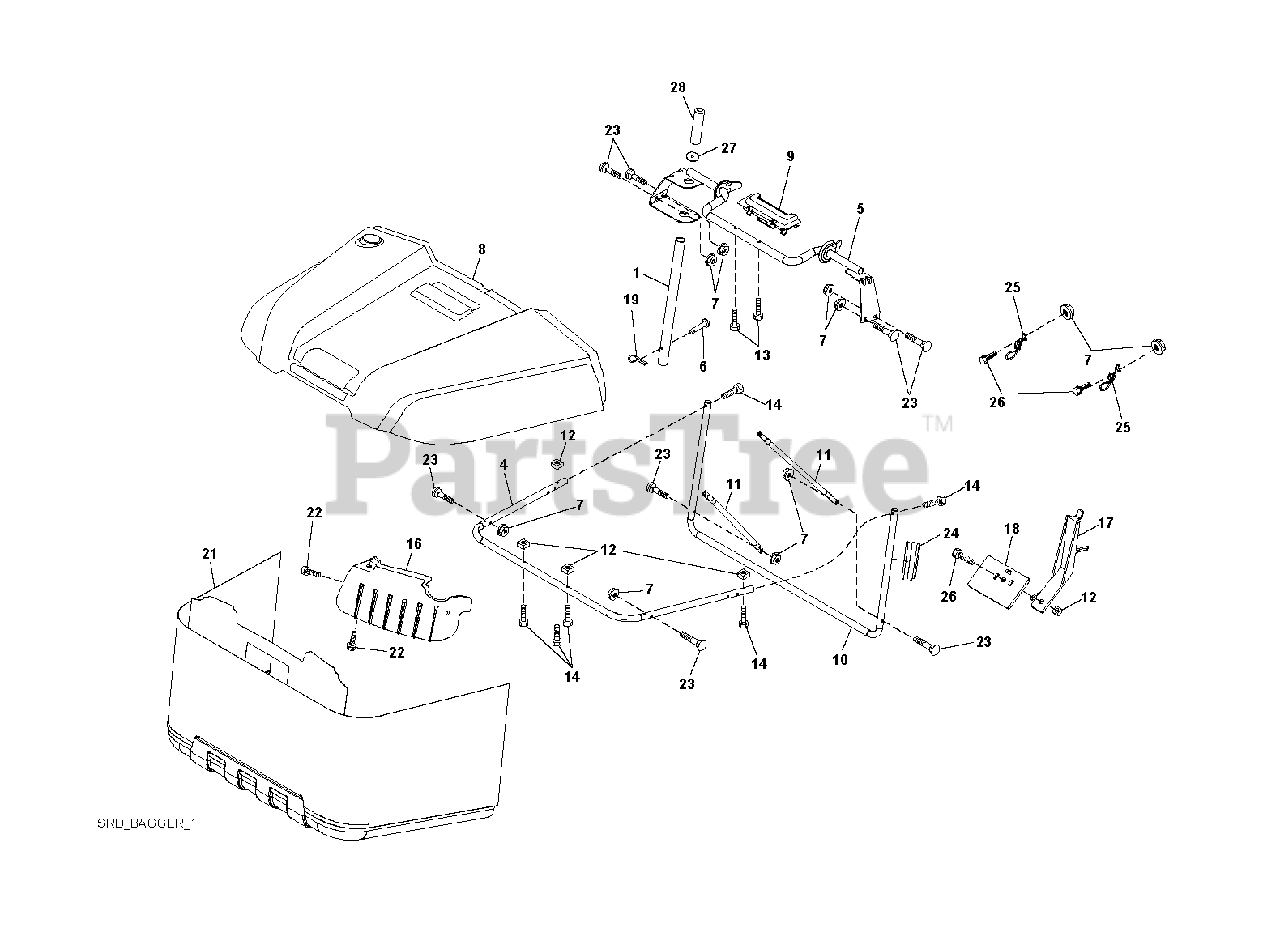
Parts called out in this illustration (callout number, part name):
1	TUBE HANDLE
6	RIVET,DRILLED
7	NUT T
19	RETAINER SPRING
22	SCREW.HI-LO.CONSOLE
26	SCREW HEX CRT
28	GRIP.HANDLE.BLACK
